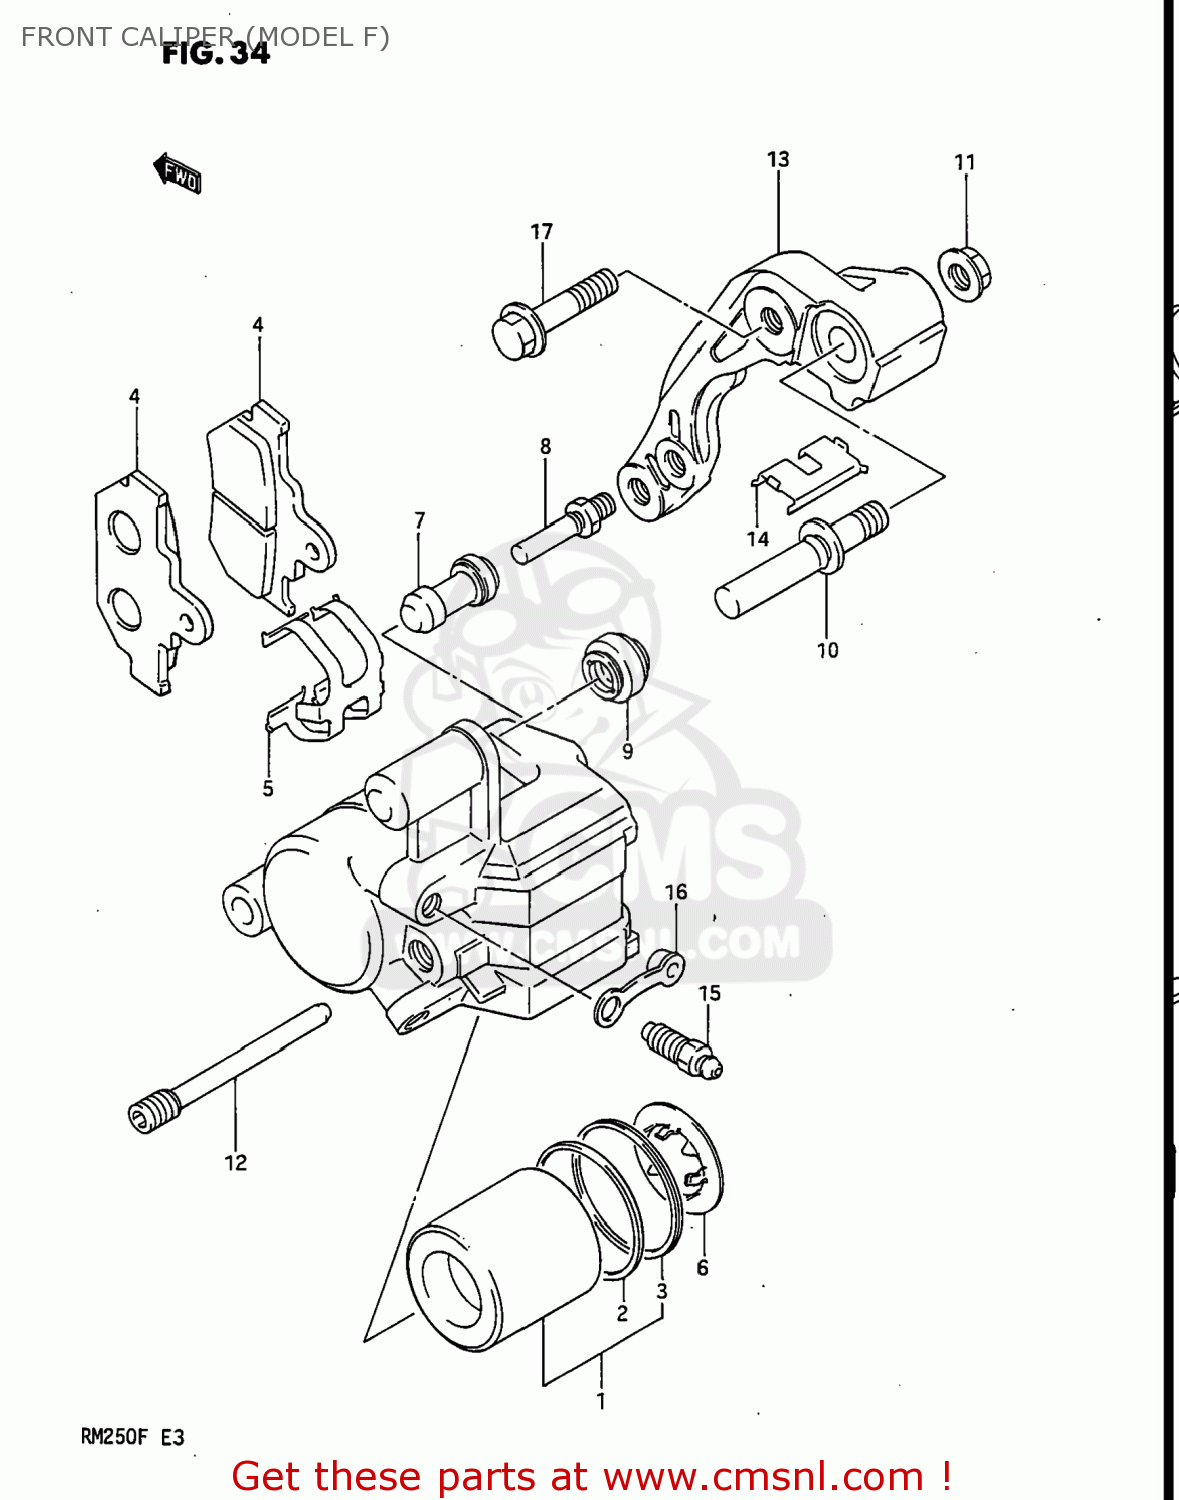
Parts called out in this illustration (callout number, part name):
1	PISTON SET,CALIPERS
2	SEAL,PISTON
3	DUST SEAL,PISTON
4	PAD
5	SPRING
6	SHIM
7	BOOT
8	PIN,BOLT
9	BOOT
10	PIN,SLIDE
11	NUT,SLIDE PIN
12	PIN,HANGER
13	BRACKET
14	RETAINER
15	BLEEDER
16	CAP,BLEEDER
17	BOLT
